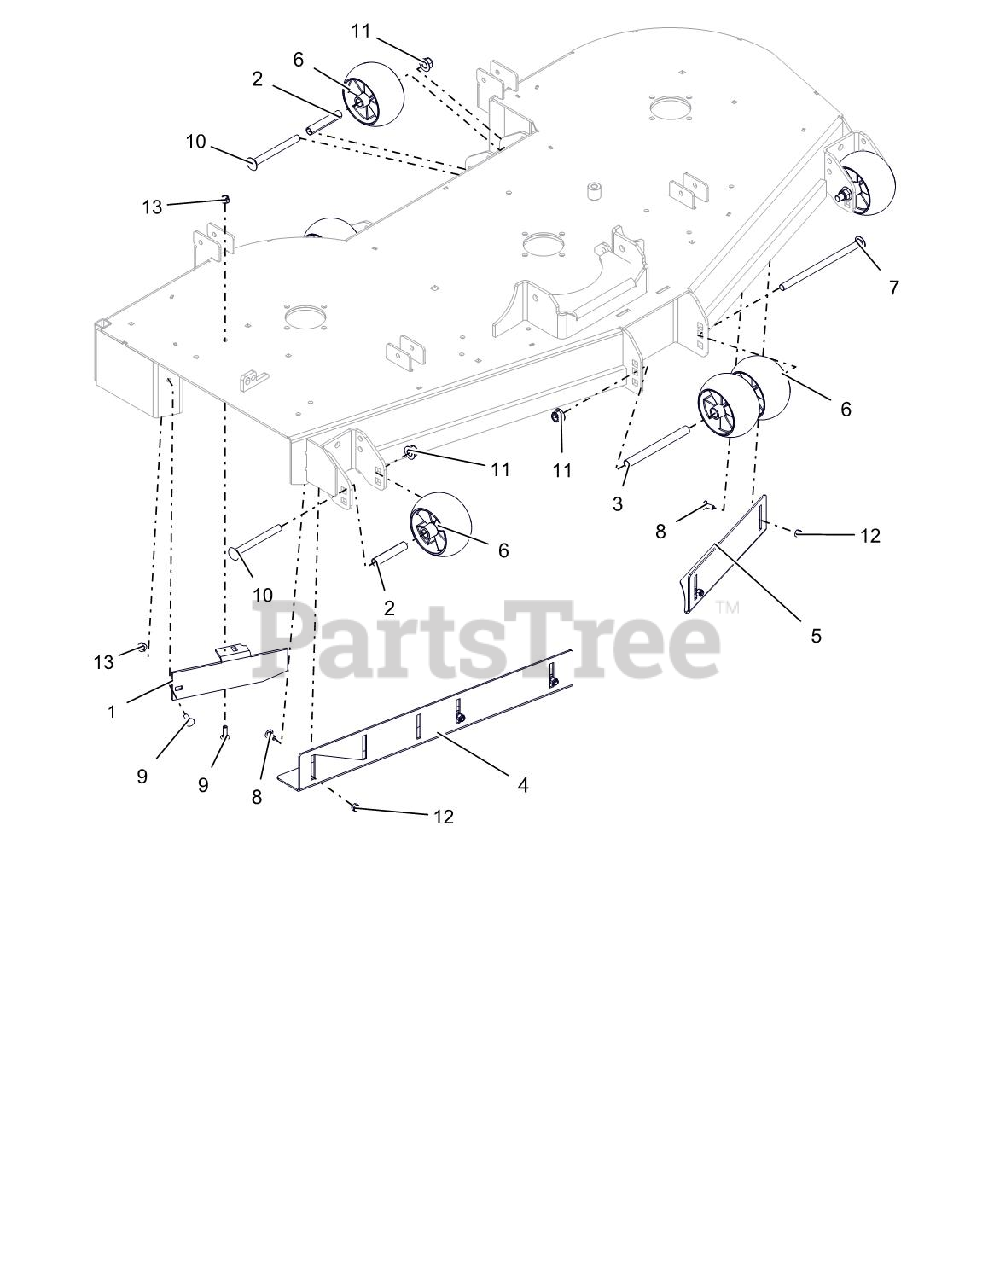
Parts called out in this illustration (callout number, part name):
1	60" DISCHARGE BAFFLE - RED
2	SPACER, .510X.625X3.35
3	SPACER, .510X.625X6.50
4	60" RH VACUUM BAFFLE - BLK
5	60" LH VACUUM BAFFLE - BLK
6	ANTI-SCALP WHEEL - 5X3 CTR
7	BLT-RDHDSQNK .50-13X8.50 G5YZ
8	BLT-RDHDSQNK .31-18X.75 G5YZ
9	BLT-RDHDSQNK .31-18X1.00 G5YZ
10	BLT-RDHDSQNK .50-13X5.00 GR5YZ
11	NUT-LK-NYL-FLG .50-13 YWZC
12	NUT-LK-NYL .312-18 YWZC
13	NUT-LK-NYL-FLG .31-18 YWZC
